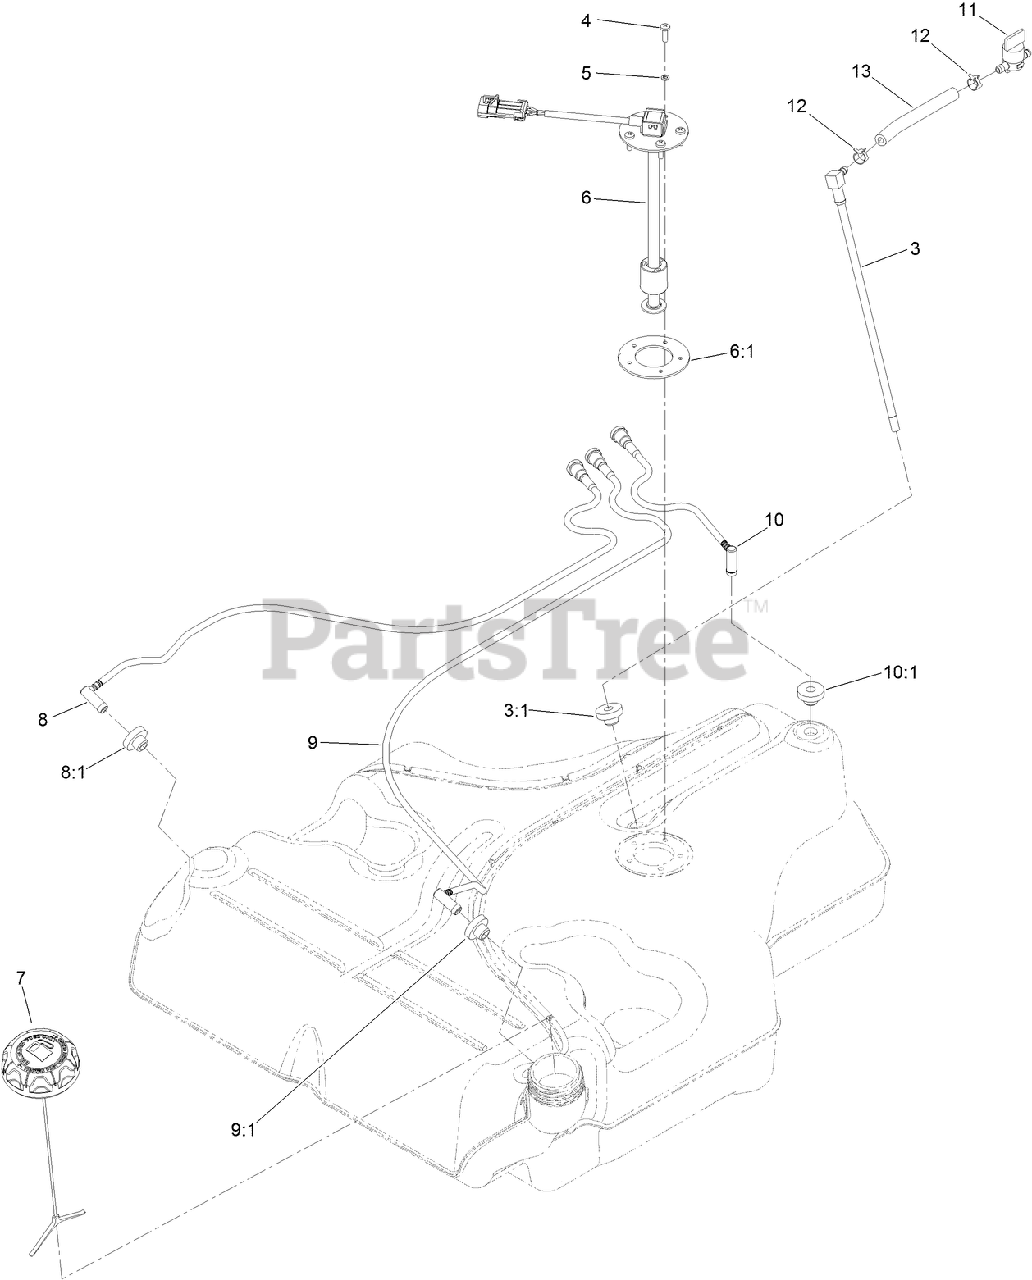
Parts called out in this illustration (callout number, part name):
3	FUEL LINE KIT (WITH GROMMET)
3:1	BUSHING
4	SCREW-PPH
5	WASHER-LOCK
6	FLOAT-SENDER, FUEL
6:1	GASKET-SENDER
7	CAP-FUEL, RATCHETING
8	RH VENT LINE KIT (WITH GROMMET)
8:1	BUSHING
9	LH VENT LINE KIT (WITH GROMMET)
9:1	BUSHING
10	REAR VENT LINE KIT (WITH GROMMET)
10:1	BUSHING
11	VALVE-FUEL
12	CLAMP-HOSE
13	HOSE-FUEL
